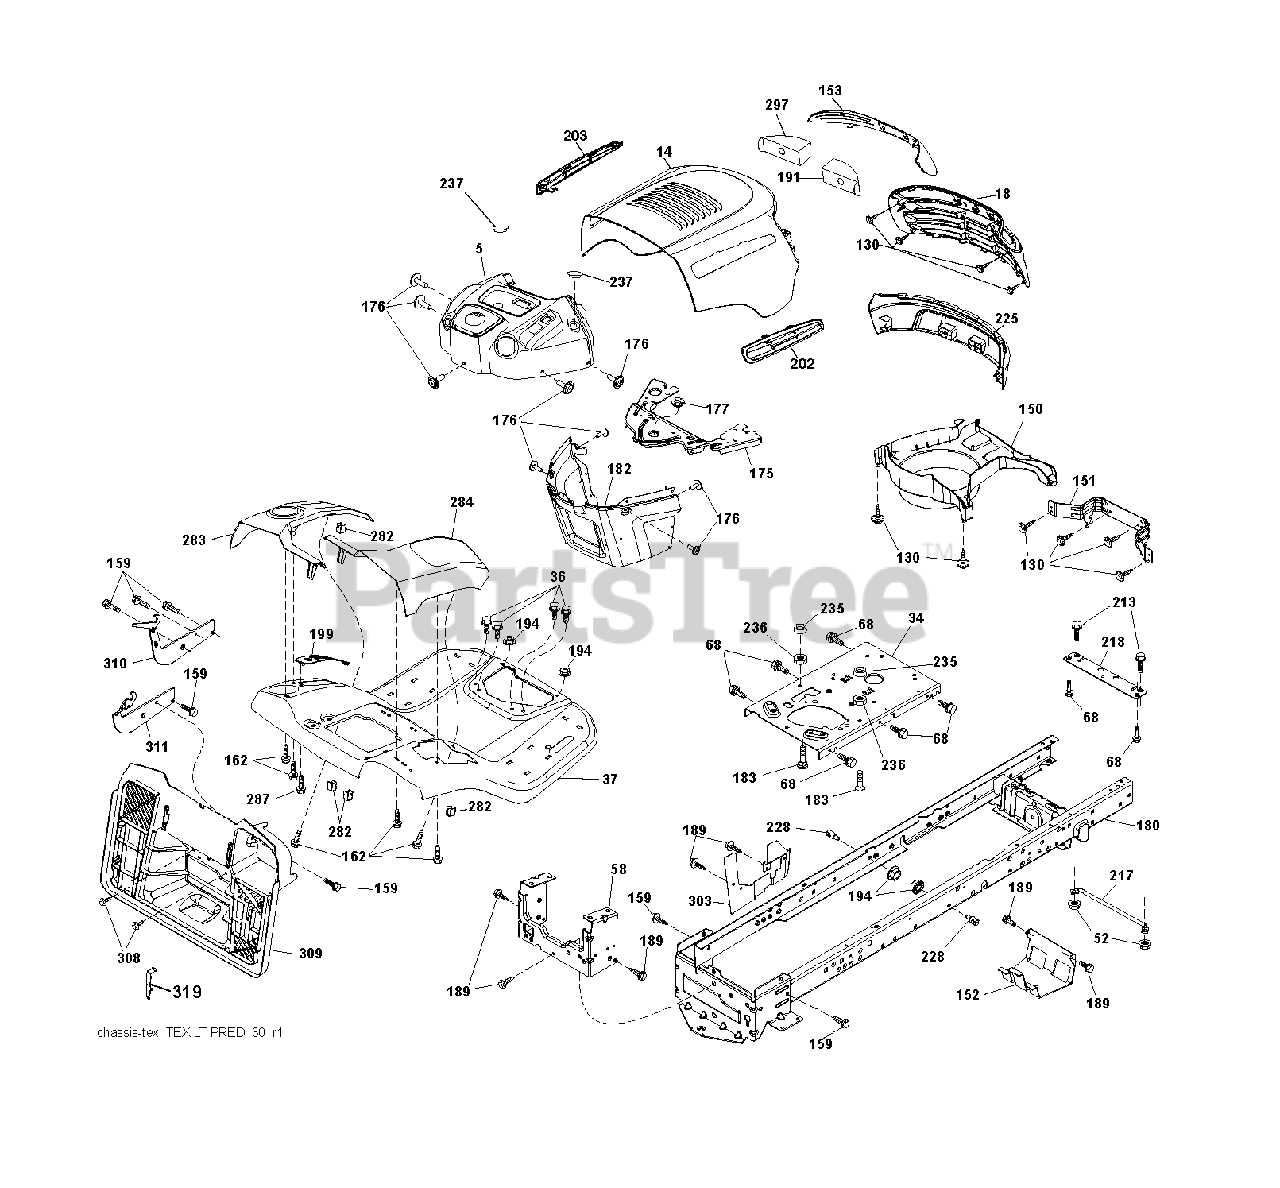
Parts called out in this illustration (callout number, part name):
5	DASH.PRED.LT.CC.ICY.SRVMDR.BLK
34	PLATE.ENGINE.WELDED.CHASSIS
36	SCREW 5/16"
52	LOCKNUT
58	DRAWBAR UPPER 2PC SMALL FENDER
130	SCREW.#10 X 0.750.BOS THREAD
151	BRACKET.PIVOT.ALPHA.LT
152	SHIELD BROWNING
159	SCREW, 3/8-16X3/4
162	SCREW.HI-LO.CONSOLE
175	CROSSMEMBER
176	SCREW.#10-24X5/8.RN.QU
177	BUSHING STEERING
182	DASH.LWER.PREDATOR/HUSQ.LT
183	BOLT.5/16-18X1-1/4 FULL.THREAD
189	SCREW
191	INSERT.REFLECT.PREDATOR.LT.RH
194	NUT LOCK HEX FLANGE 5/16-18
213	BOLT
217	ROD.PIVOT.HOOD
218	X-PIECE.HOOD.STOP.NON/
228	STUD.FASTNER.W/ANTI-ROTATE
235	SPACER FENDER
236	NUT.CENTERLOCK.5/16-
237	PLUG.MOUNT.CARGO.BLK
282	CLIP.RETAINER.CONSOLE.LT.HUSQ
297	REFLECTOR.INSERT.PRED.LH.LT
308	BOLT, 5/16-18 X 1 3/4
